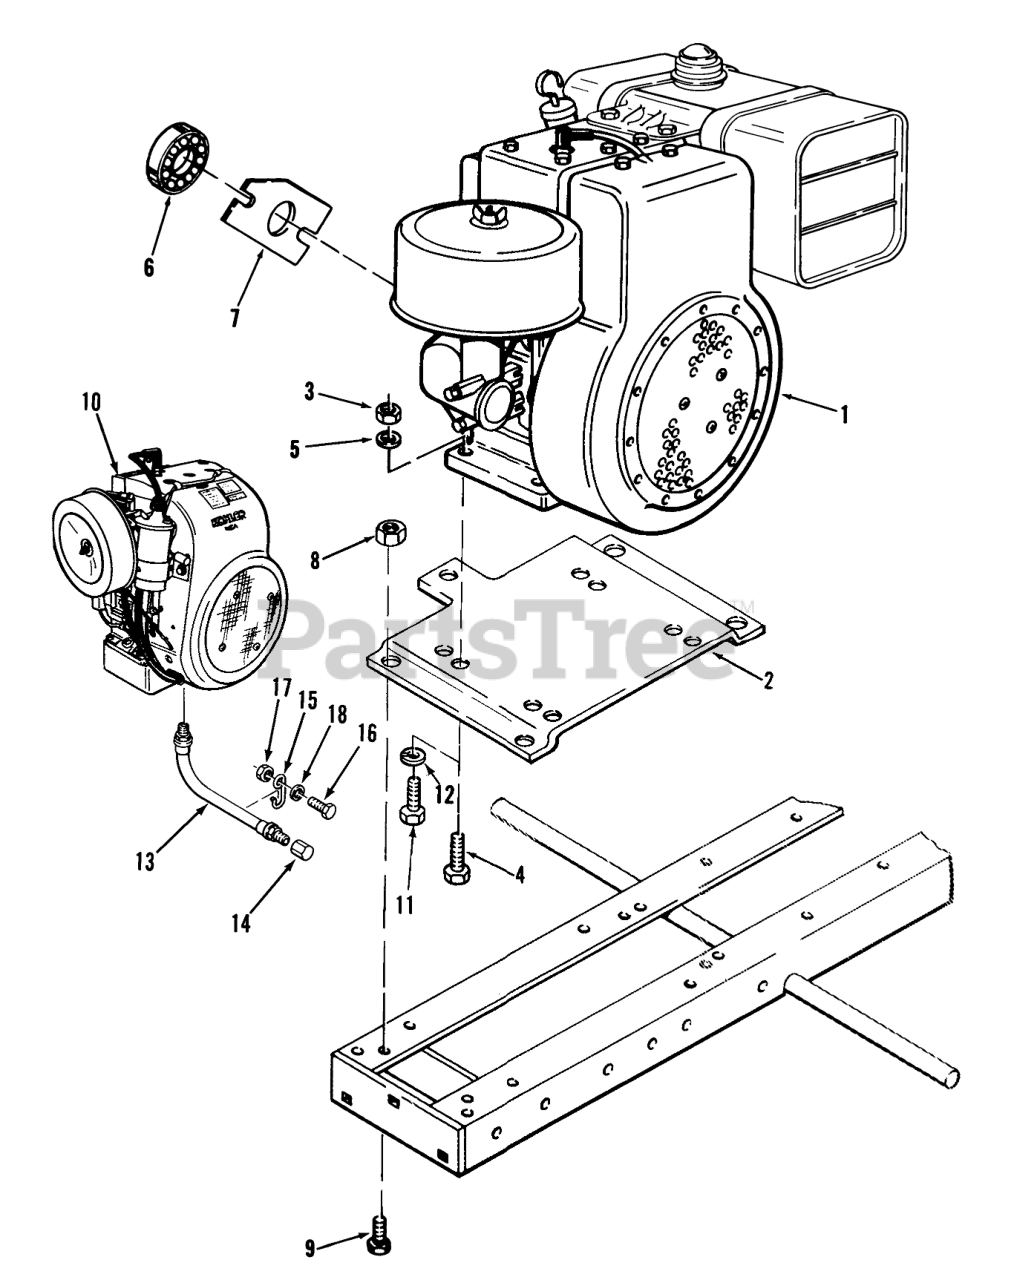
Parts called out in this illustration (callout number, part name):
1	Engine-11 HP Briggs & Stratton 252417 Type 0245-01
2	Engine Cradle
2	Engine Cradle SK-486
3	Nut
4	HHCS
5	Lockwasher
6	BEARING-BALL
7	PLATE-THRUST B
8	NUT
9	BOLT
10	Engine-16 HP Kohler K-341AS Spec 71311
11	Bolt
12	LOCKWASHER
13	ASM-HOSE
14	CAP 1/4 PIPE
15	RETAINER-HOSE
16	Bolt
17	Nut
18	Washer
